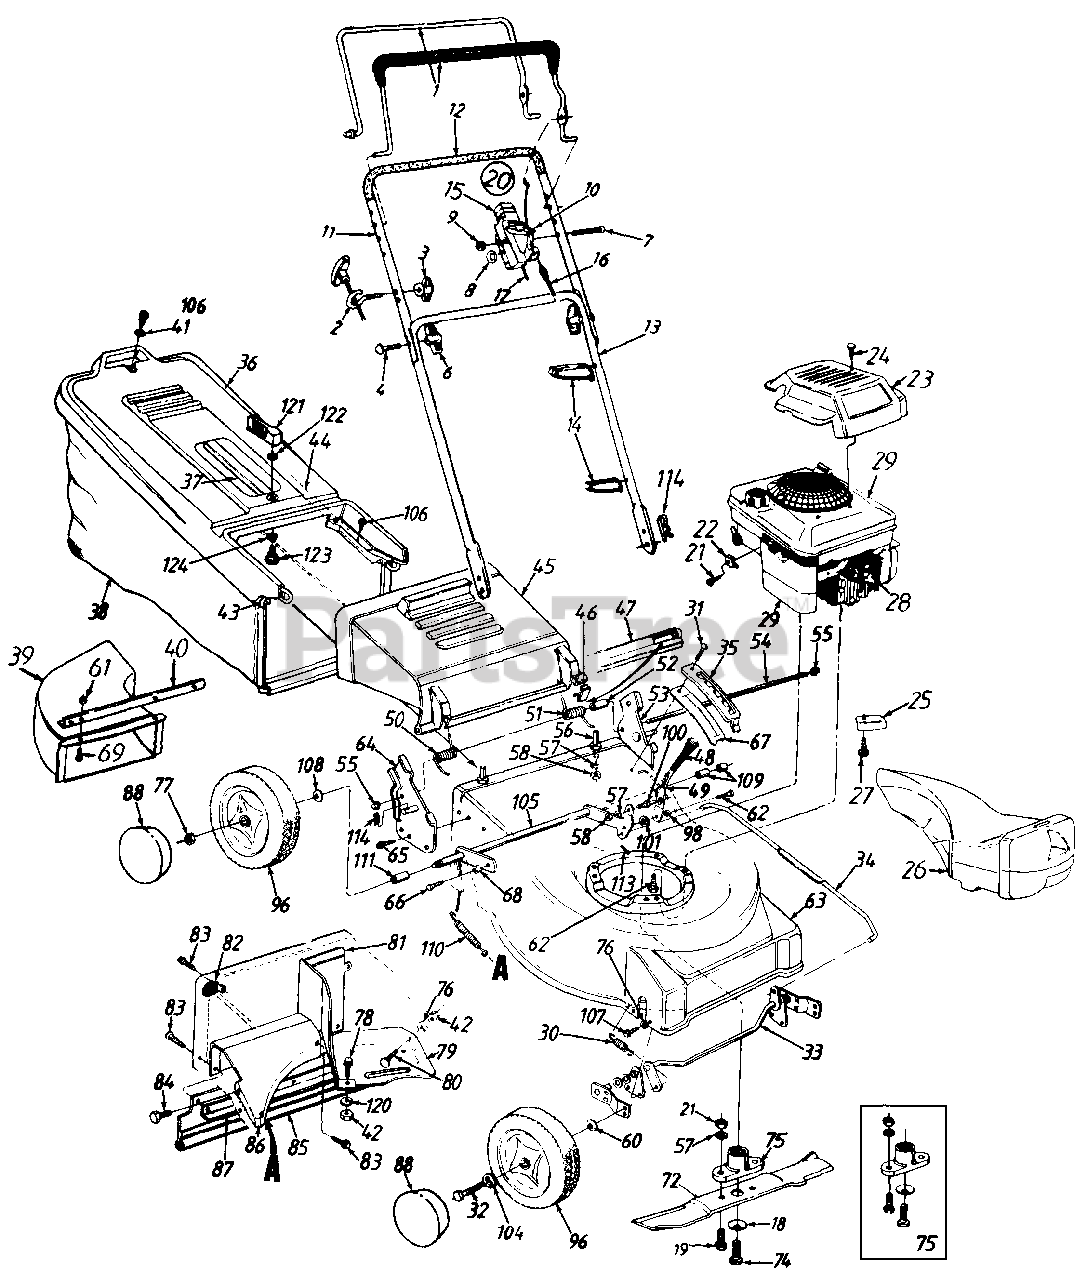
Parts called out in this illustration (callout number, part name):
2	Rope Guide
3	Handle Knob 1/4-20 Thd.
4	Curved Hd. Bolt 5/16-18 x 2" Lg.
6	Hand Knob
7	Oval C-Sunk Mach. Scr.
8	Spr. Wash .66" I.D.
9	Hex L-Nut 1/4-20 Thd.
10	Throttle Lever
14	Cable Tie
15	Throttle Body
16	Control Cable
17	Throttle Control Wire - 55"
18	Bell-Wash .46" I.D.
19	Hex Bolt 3/8-24 x 1" Lg.
20	Throttle Box Comp.
21	Hex Self-Tap Scr. #10-32 x .62" Lg.
22	Cable Clamp
23	XTE Black Shroud
24	Hi-Lo Scr. #10 x 1.25" Lg.
25	Stop Bracket
26	Mulching Plug
27	Hex Tap Scr. 3/8-16 x .75" Lg.
28	Spark Plug Boot
29	Engine
30	Extension Spring 2.39" Lg.
31	Torx Hd. AB-Tap Scr. 1/4 x .62" Lg.
32	Axle Bolt
34	Height Adj. Connecting Rod
35	Height Adjustment Plate
36	Hardtop Bag Cover
37	Hardtop Handle
38	Grass Bag
39	Chute Deflector
41	Fl-Wash .281" I.D. x .62" O.D.
42	Hex Nut 1/4-20 Thd.
45	Chute Deflector
46	Deflector Plug
47	Seal - Extrusion
49	Spring Lever
50	Torsion Spring - R.H.
51	Torsion Spring - L.H.
52	Spacer .255" I.D.
53	Handle Brkt. Ass'y.- L.H.
54	Hinge Pin 17.75" Lg
55	Cap Speed Nut
56	Shld. Pin 3/8-24 x 1.43" Lg.
57	L-Wash 3/8" I.D.
58	Hex Jam Nut 3/8-24 Thd.
60	Bell-Wash .38" I.D. x .88" O.D.
61	Hex L-Nut 1/4-20 Thd.
62	Hex L-Wash. Hd. Scr. 3/8-16 x 1" Lg.
63	21" Deck Ass'y
64	Handle Brkt. Ass'y.- R.H.
65	Hex L-Wash Hd AB-Tap Scr. 1/4 x 62" Lg.
66	Hex Wash. Hd. Tap Scr. 3/8-16 x .75" Lg.
67	Height Adjustment Support
68	Spacer 385" I.D.
69	Mach. Scr 1/4-20 x 5" Lg
72	21" Blade
74	Hex Bolt 7/16-20 x 1.5" Lg.
75	Blade Adapter Kit
76	L-Wash 1/4" I.D.
77	Hex Jam Nut 1/2-20 Thd.
78	Hex Bolt 1/4-20 x .85" Lg.
83	Torx Mach. AB-Tap Scr. 1/4 x .62" Lg.
84	Hex B-Tap Scr. 1/4 x 38" Lg.
85	Rear Flap
96	Wheel Ass'y. Comp.
98	Shld. Spacer .50" Dia.
100	Shld. Pin 3/8-24 x 1.43" Lg.
101	Fl-Wash .375" I.D. x 1.0"
104	Wave Wash .53" I D. x .78"
105	Rear Axle Ass'y
106	Hex L-Wash. AB-Tap Scr. 1/4 x .62" Lg.
107	Hex L-Wash HD AB-Tap Scr. 1/4 x .38" Lg.
108	Fl-Wash .510" I.D. x .75"
109	Spacer .526" I.D.
110	Extension Spring 3.8" Lg.
111	Sleeve .526" I.D.
113	Cotter Pin 3/32" Dia. x 75"
114	Internal Cotter Pin 5/16" Dia
120	Bell-Wash 1/4" I.D
121	Grass Catcher Locking Knob
122	Internal L-Wash. 1/4" I.D.
123	Shld. Bolt .342" Dia x .268"
124	Wave Washer 3/8" I.D.
